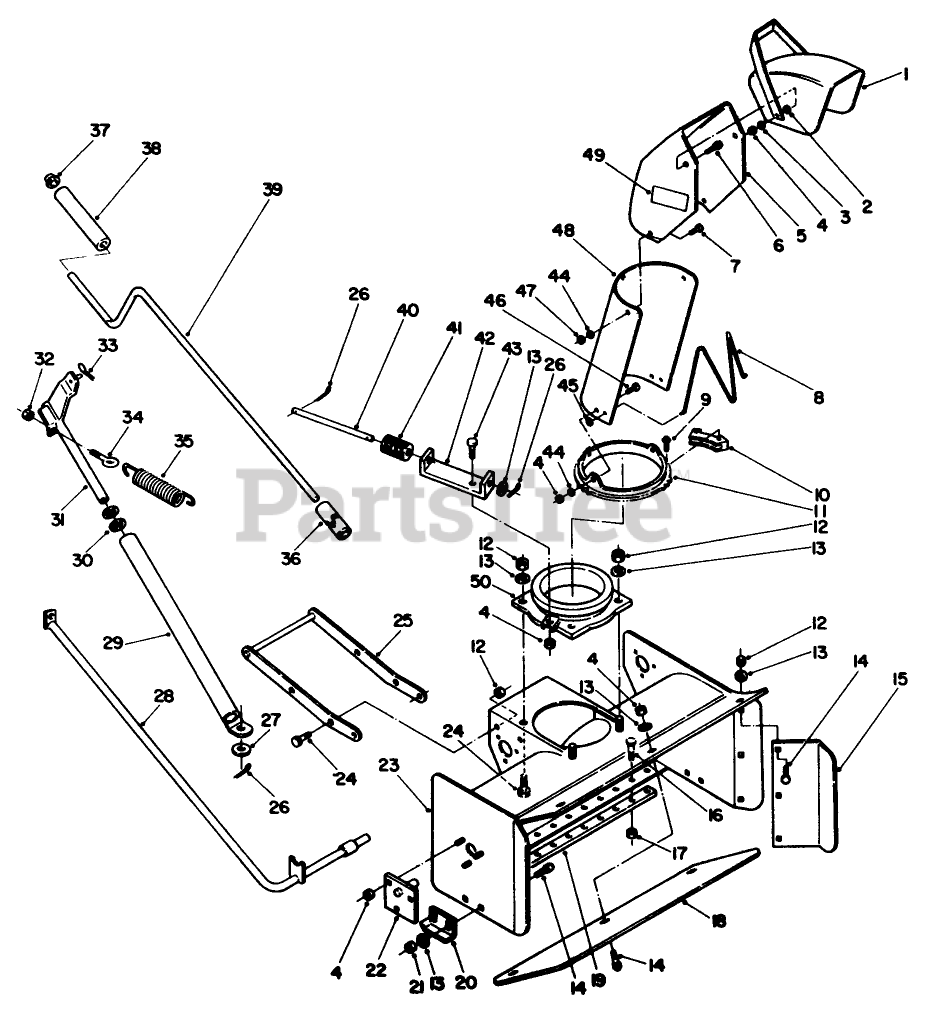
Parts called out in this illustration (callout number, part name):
1	Deflector
2	WASHER-RUBBER
3	WASHER-BELLEVILLE
4	NUT-LOCK, NI
5	Chute-Upper
6	BOLT-CARR
7	CARRIAGE BOLT -4
8	WIRE-CHUTE
9	SCREW-SPECIAL
10	RETAINER-CHUTE
11	Ring-Swivel
12	NUT-LOCK, NI
13	WASHER-FLAT
14	Bolt
15	Plate
16	SCREW-CARR
17	NUT-LOCK, NI
18	Plate
19	Reversible Scraper
20	Skid
21	NUT-LOCK, NI
22	Plate
23	Wrapper
24	SCREW-HH
25	Frame-Mounting
26	PIN-COTTER
27	WASHER-FLAT
28	Crank Support
29	SNOW THROWER COM PKG
30	Washer
31	LIFT ROD ASM
32	NUT
33	Hairpin Cotter
34	EYEBOLT
35	SPRING
36	Universal
37	RETAINER-PUSH ON
38	GRIP-CONTROL, CHUTE
39	ROD-CHUTE CONTROL
41	GEAR-WORM, CHUTE
42	Bracket-Worm
43	BOLT-CARR
44	WASHER 5/16 SAE
45	NUT-PUSH
46	SCREW-HH
47	NUT-LOCK, NI
48	Chute-Extender
49	DECAL DANGER
50	Adapter
